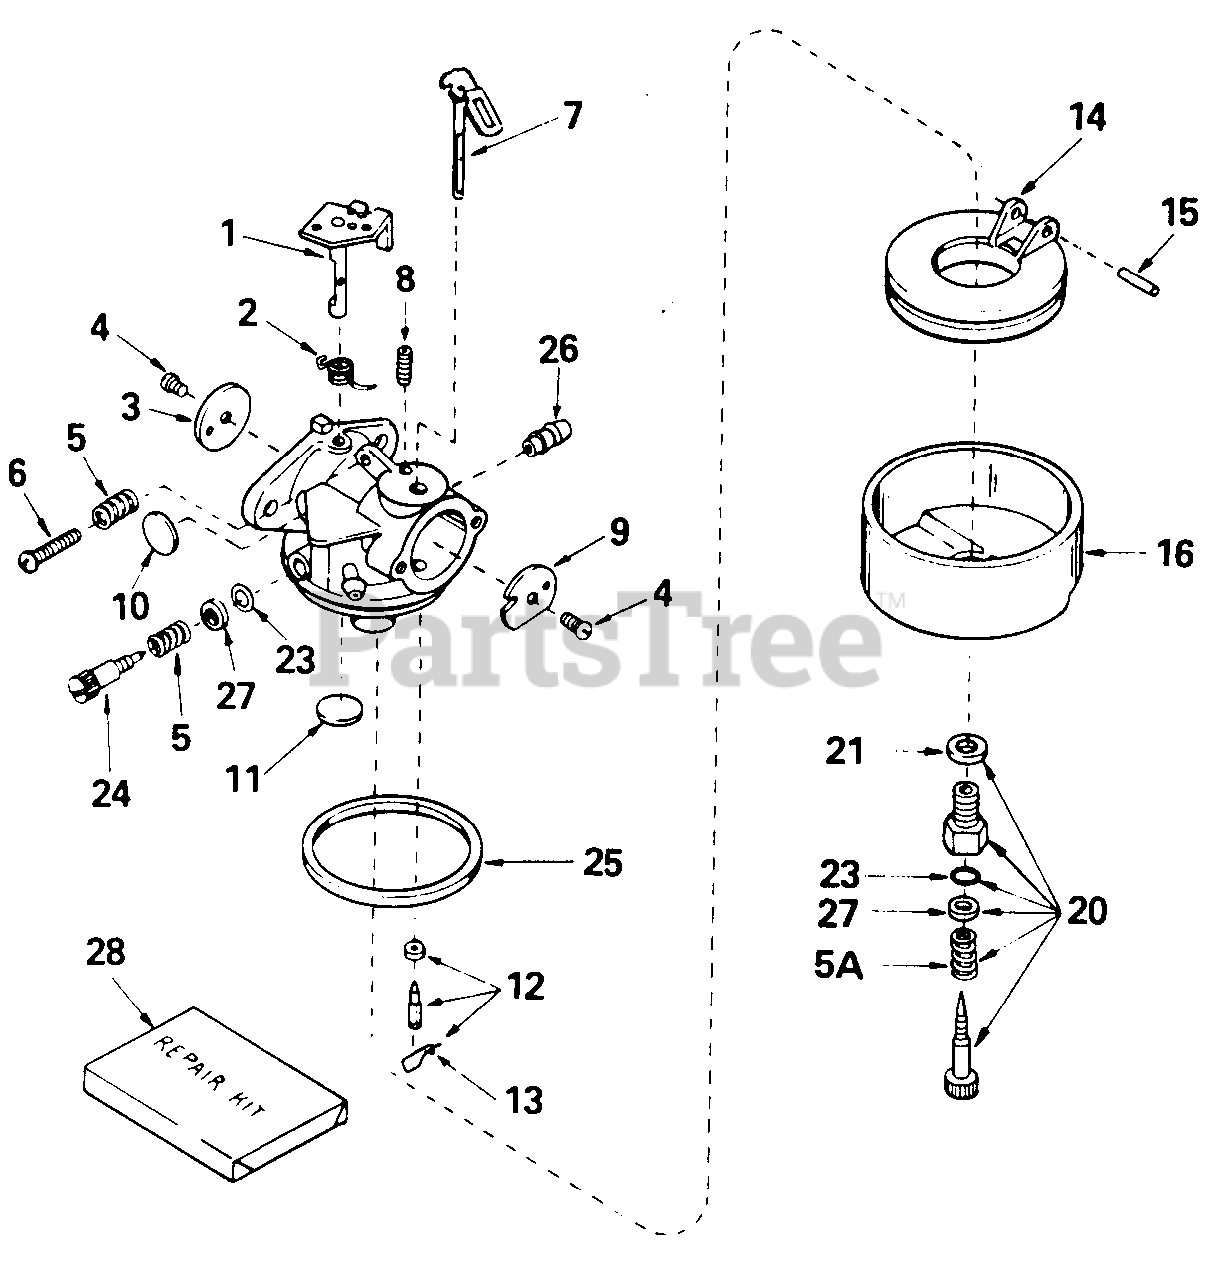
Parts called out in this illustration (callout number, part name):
1	Shaft & Lever Ass'y., Throttle
2	Spring, Throttle Return
3	Shutter, Throttle
4	Screw, Throttle & Choke Shutter
5	Spring, Regulating Screw
5A	Spring, Main Adjustment Screw
6	Screw, Idle Regulating
7	Shaft & Lever Ass'y., Choke
8	Spring, Choke Positioning
9	Shutter, Choke
10	Plug, Welch
11	Plug, Welch
12	Inlet Needle, Seat & Clip Ass'y.
13	Clip, Inlet Needle
14	Float, Carburetor
15	Shaft, Float
16	Bowl, Float
20	Adjustment Screw Ass'y., Main
21	Gasket, Bowl-to-Body
23	"O"-Ring, Adjustment Screw
24	Screw, Idle Adjustment
25	Gasket, Bowl-to-Body
26	Fitting, Fuel Inlet
28	Repair Kit
